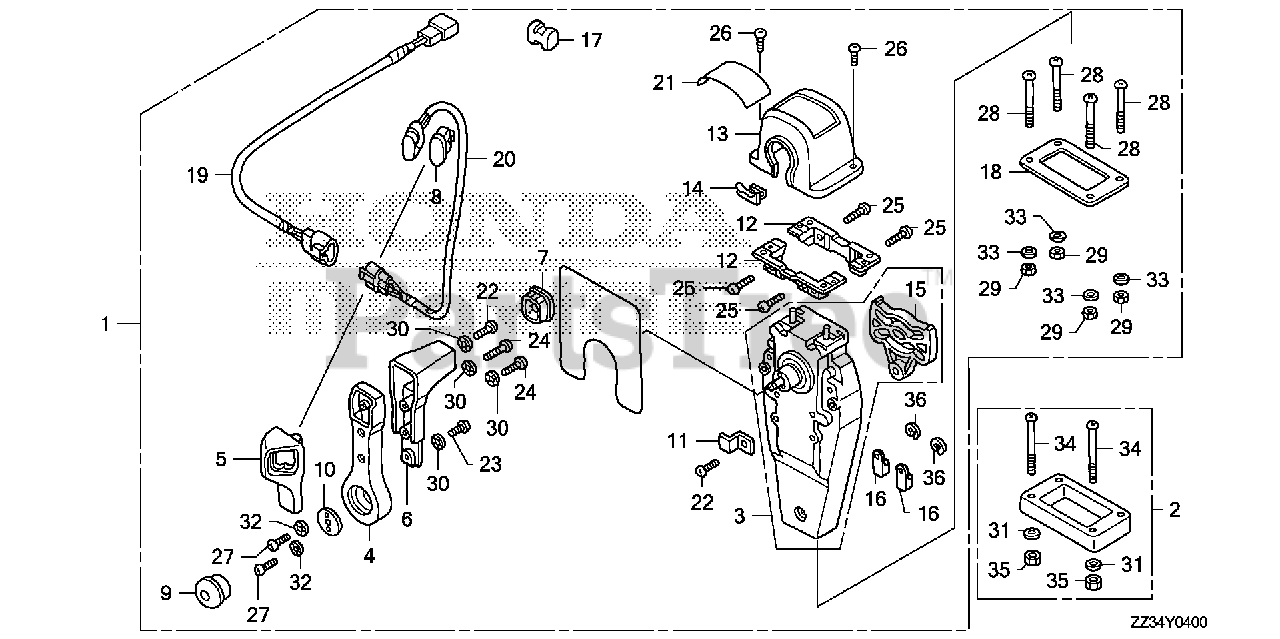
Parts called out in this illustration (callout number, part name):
1	BOX KIT, REMOTE CONTROL (TOP MOUNT SINGLE)(R)
2	SPACER KIT, REMOTE CONTROL BOX (TOP MOUNT SINGLE)
3	HOUSING ASSY., L. (INNER) (TOP MOUNT)
4	HANDLE, REMOTE CONTROL
5	COVER, L. GRIP
6	GRIP, REMOTE CONTROL HANDLE
7	CAP, GRIP
8	CAP, SWITCH
9	BUTTON, THROTTLE
10	PLATE, HANDLE
11	PLATE, CABLE CLAMP
12	BRACKET, REMOTE CONTROL HOUSING
13	HOUSING, REMOTE CONTROL BOX
14	HOUSING, LEAD
15	PLATE, DWELL
16	TERMINAL, CABLE
17	SPACER, CABLE CLAMP
18	GASKET, SINGLE
19	SUB-HARNESS ASSY., POWER TRIM-TILT (A)
20	SWITCH ASSY., POWER TRIM-TILT (A)
21	MARK, REMOTE CONTROL (SINGLE)
22	SCREW, PAN (5X16)
23	SCREW, PAN (5X10)
24	SCREW, PAN (5X20)
25	SCREW, PAN (5X18)
26	SCREW, PAN (4X10)
27	SCREW, PAN (6X18)
28	SCREW, PAN (5X40)
29	NUT, HEX. (5MM)
30	WASHER, LOCK (5MM)
31	WASHER, PLAIN (5MM)
32	WASHER, LOCK (6MM)
33	WASHER, PLAIN (5MM)
34	SCREW, PAN (5X65)
35	NUT, HEX. (5MM)
36	E-RING (6MM)
